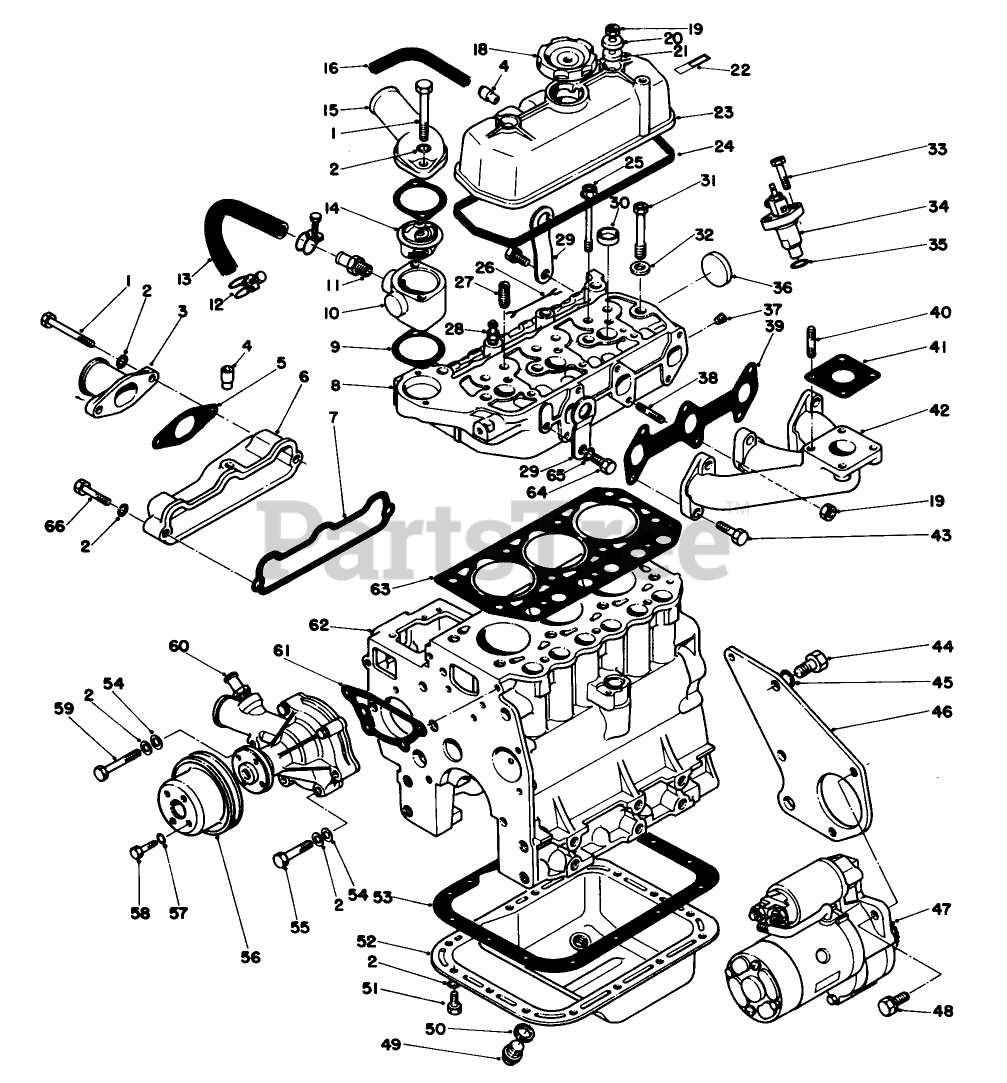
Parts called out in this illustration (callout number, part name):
2	WASHER-LOCK, SPRING
3	INLET PIPE MM 408564
5	GASKET MM 408566
6	MANIFOLD MM 408541
7	GASKET
8	Head Assembly, Cylinder
9	GASKET
10	FITTING
11	HOSE NIPPLE
12	HOSE CLAMP MF 661011
13	Hose, Water (Incl. Ref. #12)
14	Thermostat
15	FITTING MD 008771
16	AIR PIPE MM 408536
18	CAP-FILLER
19	NUT-HEX
20	WASHER
21	OIL SEAL MD 000523
22	Label-Engine No.
23	COVER ASM MM 408491
24	COVER GASKET
25	CYL HD BOLT
26	LEAD WIRE K 9670260
27	VALVE GUIDE
28	GLOW PLUG (12V)
29	ENG HANGER MM 408470
30	SEALING CAP
30	ADJ SCREW K 7231220
31	CYL HD BOLT
32	CYL HD BOLT WASHER
34	Nozzle & Holder Assembly
35	HLDR GASKET K 6515430
36	SEALING CAP
37	1/8 PLUG MS 661120
39	GASKET
41	GASKET
42	MANIFOLD
43	Screw-HH
44	BOLT/WASHER
45	WASHER-LOCK, SPRING
46	REAR PLT MM 408257
47	Starter Assembly
48	SCREW-HH
49	DRAIN PLUG
50	GASKET-PLUG
51	BOLT
52	Pan Assembly Oil (Incl. Ref. #49 & 50)
53	PAN GASKET
54	WASHER
55	Capscrew
56	PULLEY K9674051 F/W
57	WASHER-LOCK, SPRING
58	SCREW - CAP
59	BOLT
60	WATER PUMP
61	GASKET
62	Block Sub Assembles Cylinder
63	CYL GASKET
64	SCREW - CAP, HH
65	WASHER-LOCK, SPRING
66	BOLT/WASHER
